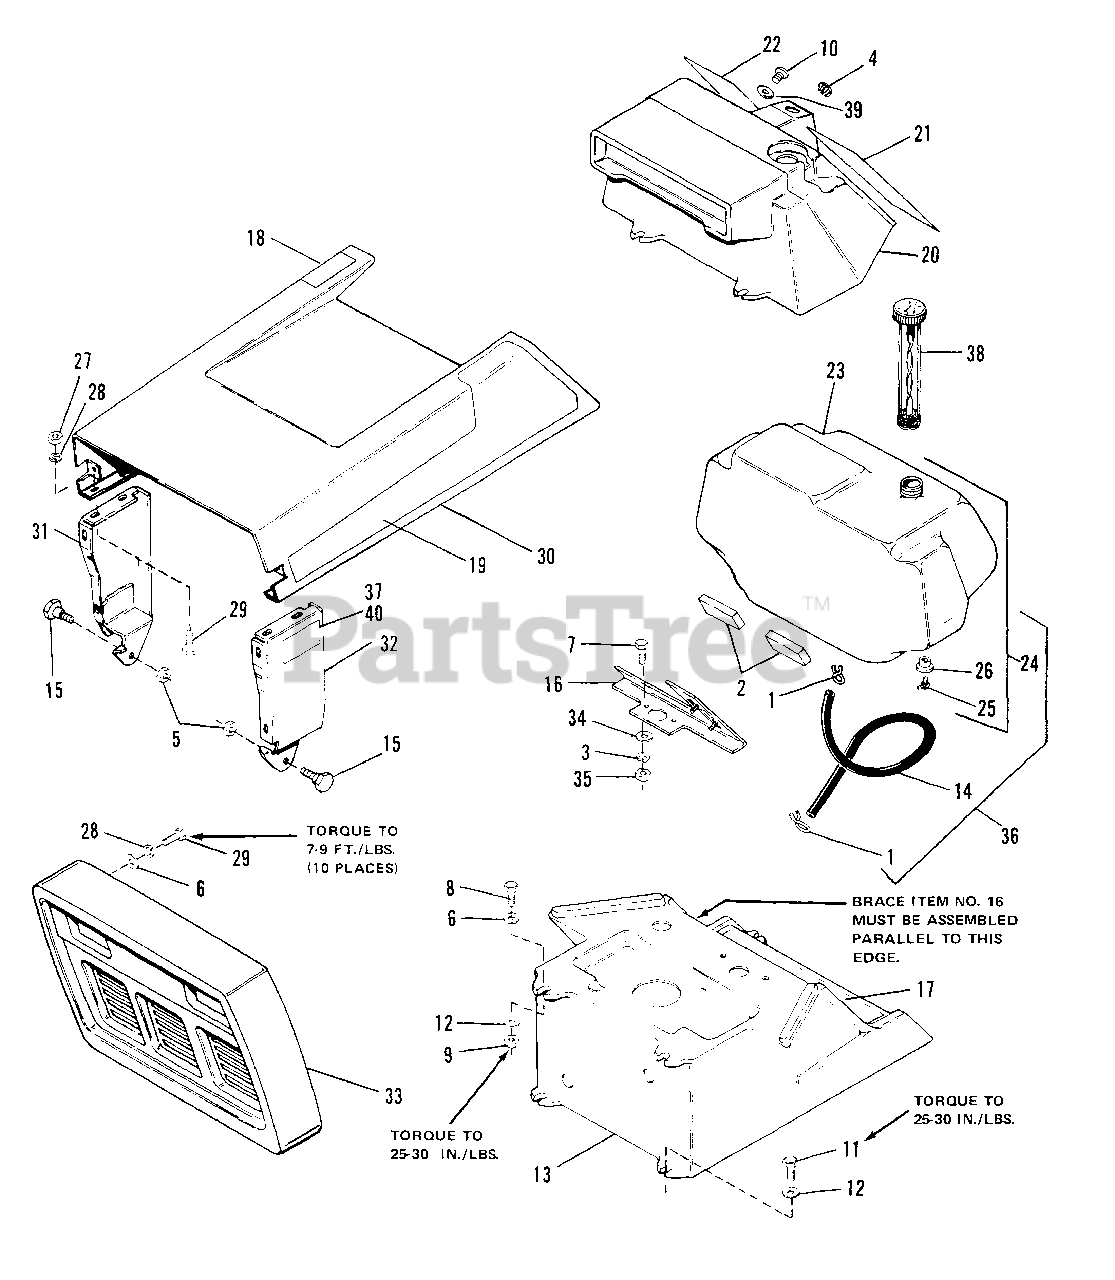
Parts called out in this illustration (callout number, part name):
1	CLAMP, Hose
2	PAD, Fuel Tank
3	LOCKWASHER, Spring, 3/8
4	CAP, Plug
5	* LOCKNUT, Flange, Whiz, 5/16-18 (10872)
6	* WASHER, Plain, 1/4 (10872)
7	CAPSCREW, Hex Hd., 3/8-16 x 1
8	CAPSCREW, Hex Hd., 1/4-20 x 1-1/4
9	LOCKNUT, Hex, 1/4-20
10	SCREW #1 4AB x 3/4
11	SCREW, Taptite Hex, 1/4-20 x 1
12	WASHER, Dish, 1/4
13	DASHBOARD, Bottom
15	* BOLT, Shoulder, 5/16-18 (10872)
16	BRACE ASSY, Dash
17	DECAL, Shift Pattern
18	DECAL, Hood, R.H.
19	DECAL, Hood, L.H.
20	DASH, Top
21	DECAL, Dash, L.H.
22	DECAL, Dash, R.H.
24	FUEL TANK SUB ASSY
27	* NUT, Hex, 1/4-20 (10872)
28	* LOCKWASHER, Spring, 1/4 (10872)
29	* CAPSCREW, Hex Hd., 1/4-20 x 1/2 (10872)
30	* HOOD (10872)
31	* PANEL ASSY, R.H. (10872)
32	* PANEL ASSY, L.H. (10872)
33	* GRILLE (10872)
34	WASHER, Plain
35	NUT, Hex, 3/8-16
36	TANK ASSY, Fuel
37	DECAL, 4111
38	CAP, Fuel Tank
40	DECAL, 4108 Electric Start
